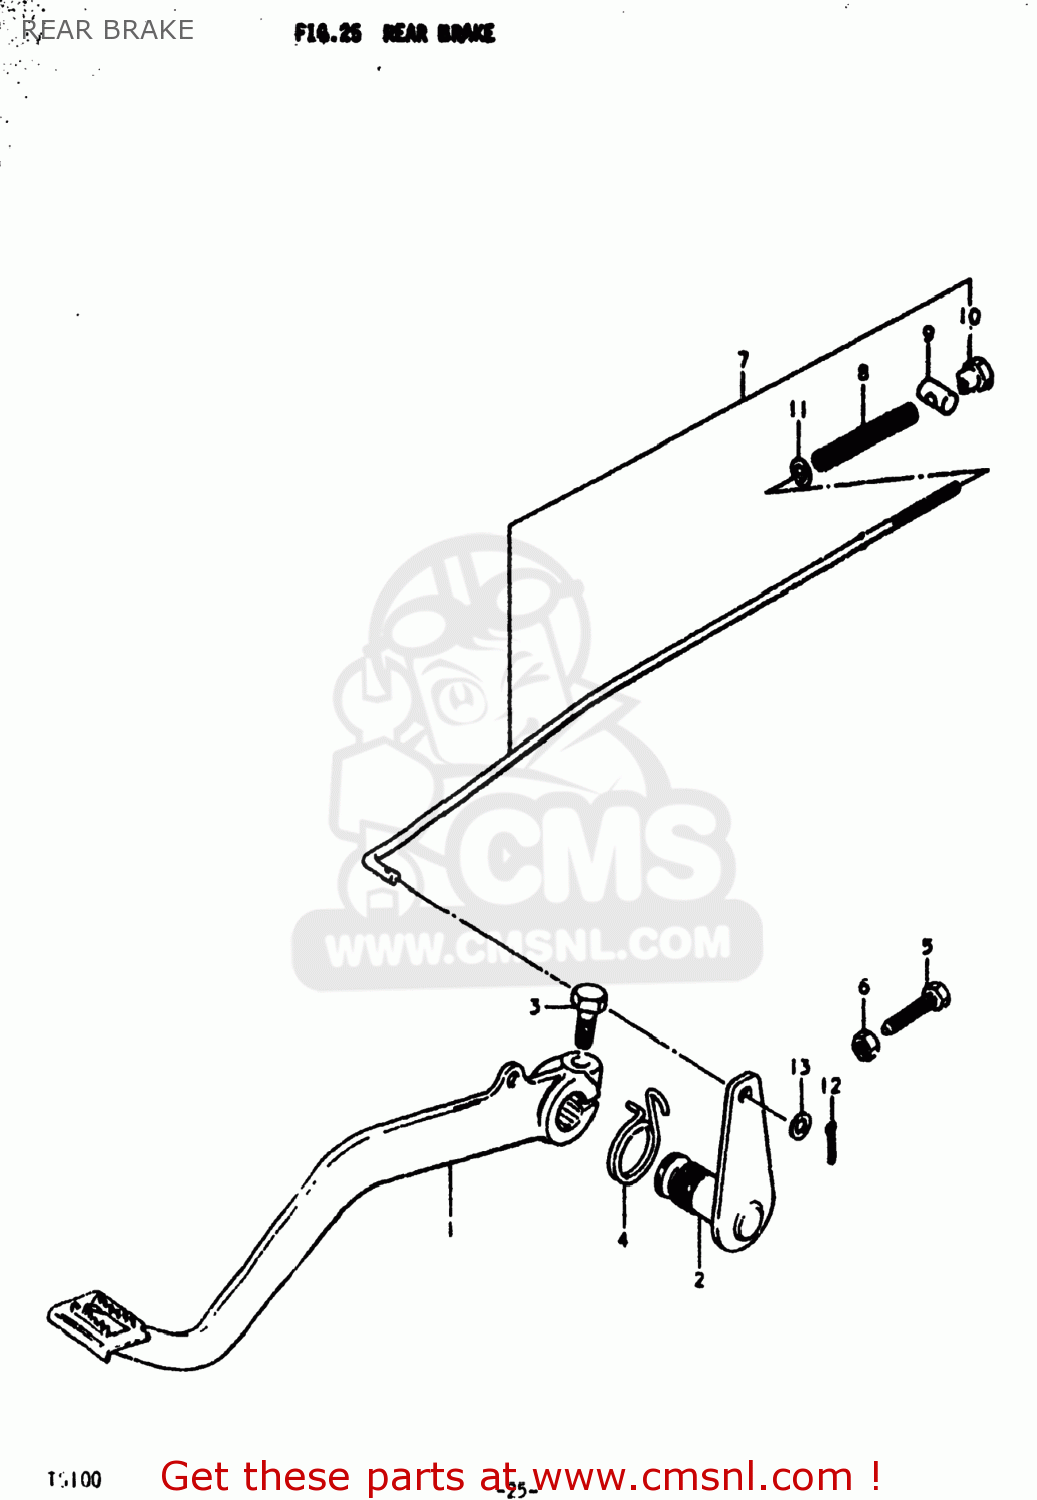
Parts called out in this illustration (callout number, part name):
1	TANK ASSEMBLY,FUEL
2	EMBLEM
3	BOLT
4	SPRING
5	BOLT(6X23)
6	NUT
7	CUSHION
8	SPRING
9	CUSHION
10	NUT
11	WASHER
12	PIN 20X20
13	WASHER
